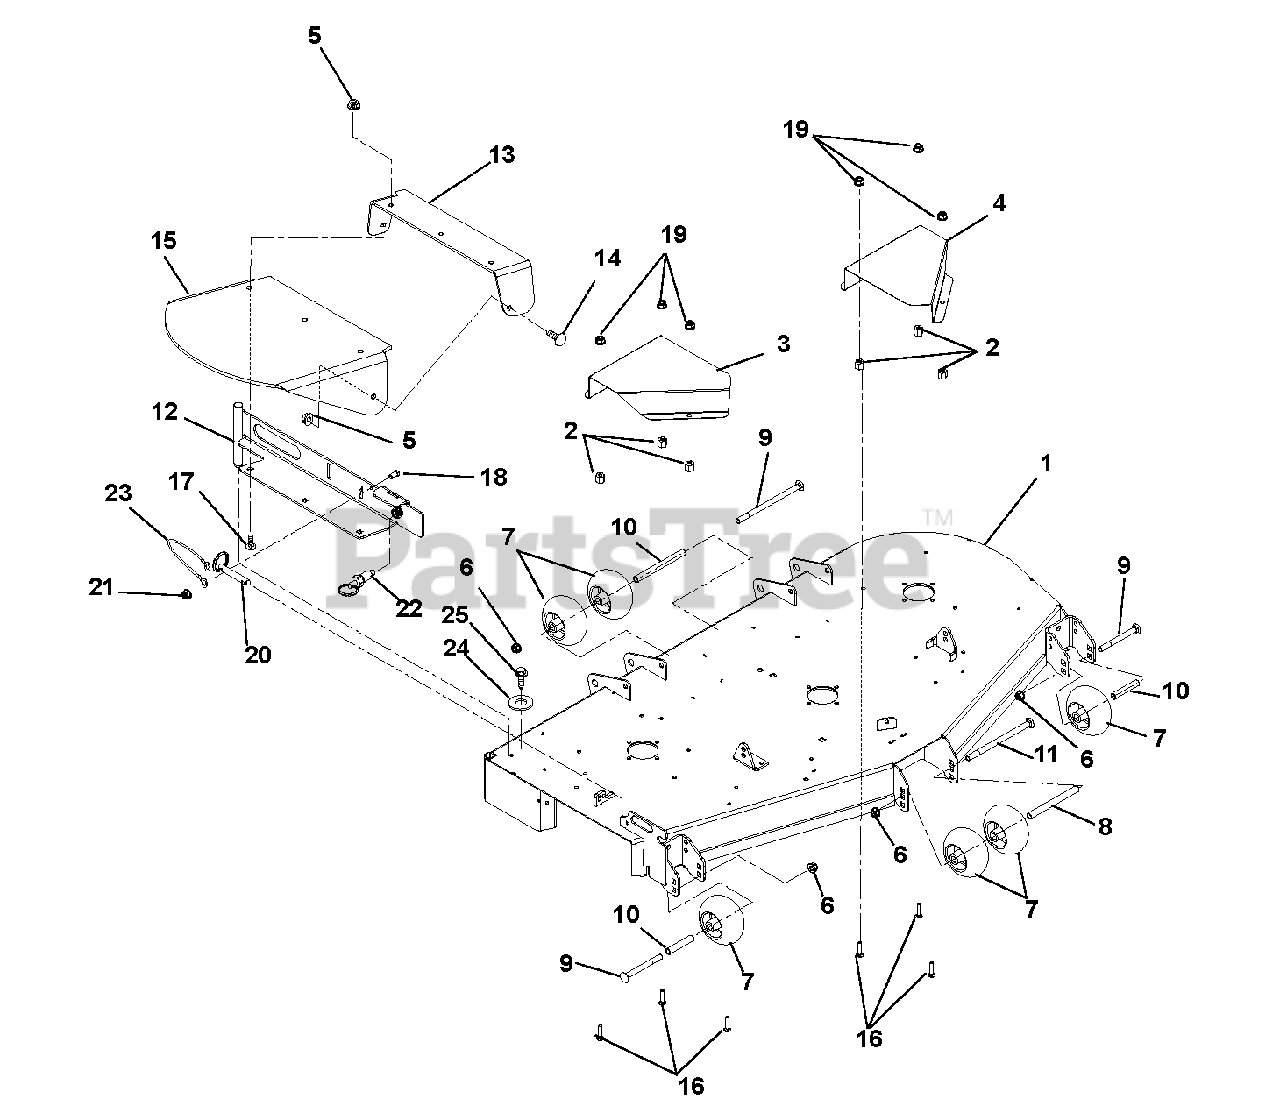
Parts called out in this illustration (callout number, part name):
1	Kit, Deck, 60" with Safety Decals (991084, 091, 101)
1	Kit, Deck, 52" with Safety Decals (991083, 100)
1	Kit, Deck, 48" with Safety Decals (991082, 099)
1	Kit, Deck, 44" with Safety Decals (991090, 098)
2	Nut, Heavy Hex .38-16
3	Guard, 60" Spindle Sheave Right Hand (991084, 091, 101)
3	Guard, 48"-52" Spindle Sheave Guard Right Hand (991082, 083, 090, 098, 099, 100)
4	Guard, 60" Spindle Sheave Left Hand (991084, 091, 101)
4	Guard, 52" Spindle Sheave Left Hand (991082, 083, 090, 098, 099, 100)
5	Nut .38-16 Nyloc Flange
6	Nut .50-13 Nyloc Flange
7	Anti-Scalp Wheel (991082, 099)
7	Anti-Scalp Wheel (991083, 084, 090, 091, 098, 100, 101)
8	Spacer, Anti-Scalp Wheel (991082, 099)
8	Spacer, Anti-Scalp Wheel (991083, 084, 090, 091, 098, 100, 101)
9	Bolt, Round Head Square Neck .50-13 x 5.00 (991082, 099)
9	Bolt, Round Head Square Neck .50-13 x 5.00 (991083, 084, 090, 091, 098, 100, 101)
10	Spacer, .510 x .625 x 3.35 (991082, 099)
10	Spacer, .510 x .625 x 3.35 (991083, 084, 090, 091, 098, 100, 101)
11	Bolt, Round Head Square Neck .50-13 x 8.50 (991082, 099)
11	Bolt, Round Head Square Neck .50-13 x 8.50 (991083, 084, 090, 091, 098, 100, 101)
12	Weldment, 44" & 48" Discharge Chute Mounting (991082, 098, 099)
12	Weldment, 52" – 60" Discharge Chute Mounting (991083, 084, 091, 100, 101)
13	Rubber Discharge Chute Support
14	Bolt, Round Head Square Neck .38-16 x 1.00 Grade 5
15	Chute, Rubber Discharge
16	Bolt, Hex .38-16 x 1.25 Grade 5
17	Bolt, Round Head Square Neck .38-16 x 1.25 Grade 5
18	Bolt, Hex .25-20 x .75 Grade 5 (991082, 090, 098, 099)
19	Nut, Flange .375-16
20	Pin, Spring Ball .375 OD x 1.50 (991082, 090, 098, 099)
21	Nut, Locking Top Flange .25-20 (991082, 090, 098, 099)
22	Pull Pin
23	Cable, 6.00 Lanyard – Nylon (991082, 090, 098, 099)
24	Bumper, Recessed 1.50 x .63 W/.31 Thru Hole
25	Screw, Tapping .31-18 x .75 Hex Washer Head
